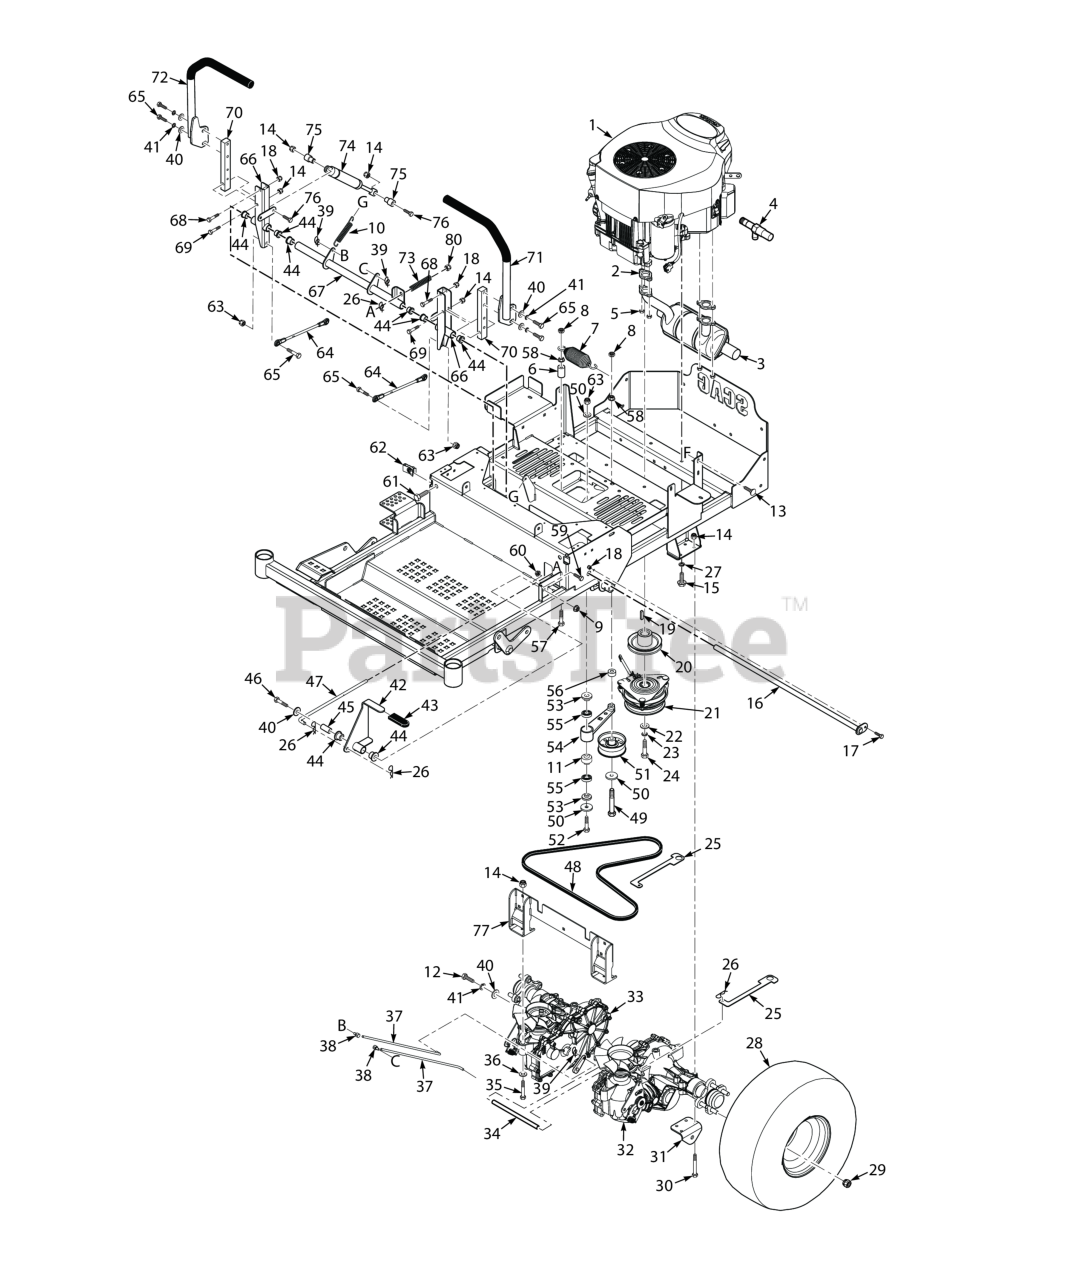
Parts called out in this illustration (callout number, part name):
1	Engine, Kawasaki - FR691V
2	Gasket, Exhaust
3	Muffler, Kawasaki FR651V & FR691V
4	Oil Drain, Kawasaki
5	Nut, M8 x 1.25 Hex Special
6	Spacer, Idler Pulley - SFZ52
7	Spring, Transmission Drive
8	Bolt, Hex Head 3/8-16 x 1" Ser. Flg.
9	Nut, Flange Elastic Stop Nut, 3/8-16
10	Spring, Deck Latch
11	Spacer, Bearing
12	Bolt, Hex Head 3/8-16 x 2-1/4" - 61"
13	Serr. Fl. Hex Head CPSCR, 1/4-20 x 3/4"
14	HEX NUT, ELASTIC STOP LOCK, 5/16-18
15	Bolt, Hex Head 3/8-16 x 1-1/4", Kawasaki FX / FS
16	Shaft Weldment, Control Arm
17	BOLT, HEX HEAD, 1/4-20 X 5/8
18	HEX, NUT, ELASTIC STOP LOCK, 1/4-20
19	Key, 1/4 x 1/4 x 1.25" Pulley Mtg.
20	Pulley, 4-1/2" - 1" Bore
21	Electric Clutch Assembly
22	Flatwasher, 7/16-.469 x 1.75 x .25 (48, 52)
23	Lockwasher, 7/16� Spring
24	Bolt, Hex Head 7/16-20 x 3¼" w/Patch
25	Lever, Dump Valve
26	HAIR PIN, .08 DIAMETER X 1-3/16"
27	Lockwasher, 3/8" Spring, Kawasaki FX / FS
28	Wheel Assembly (48, 52)
30	Bolt, Hex Head 5/16-18 x 3.00"
32	Transaxle, LH - SZL
33	Transaxle, RH - SZL
34	Spacer
35	BOLT, HEX HEAD, 5/16-18 X 2-1/4
37	Rod, Brake
39	Pin, Rue Cotter 3/8" Diameter
40	Flatwasher, 3/8" Special (.391 x .938 x .105)
41	Lockwasher, 3/8" Spring, Kawasaki FX / FS
42	Brake Lever Assembly
43	Grip, Brake Handle
44	Bearing
45	Pivot, Brake Lever
46	Capscrew, Hex Head 3/8-16 x 2-1/2"
47	Rod, Upper Brake Linkage
48	Belt, Transmission -SZL
49	Capscrew, Hex Head 3/8-16 x 3-3/4"
50	Flatwasher, 3/8 (.391 x .938 x .105 HD) Grade 8
51	Pulley, 3-1/2" Dia.
52	Bolt, Hex Head 3/8-16 x 3" - 52"
53	Spacer, Controls
54	Trans. Idler Arm Assy. (Includes 24, 79)
55	BEARINGS, BALL, NEUTRAL RETURN
56	Spacer, Idler Pulley - SFZ61
57	Capscrew, Hex Head 3/8-16 x 2.0"
58	NUT, 3/8-16 SERRATED FLANGE HEX HEAD
59	Capscrew, Hex Head 1/4-20 x 1"
60	NUT, 1/4-20 SERRATED FLANGE HEX HEAD
61	Bolt, Hex Head 3/8-16 x 2-1/2" Soecial Lock
62	U-Nut, 3/8-16
63	HEX NUT, ELASTIC STOP LOCK, 3/8-16
64	Linkage, Pump
65	Bolt, Hex Head 3/8-16 x 1-1/4", Kawasaki FX / FS
66	Bolt, Hex Head 3/8-16 x 1-3/4" (Kohler EFI)
67	Control Arm Assembly
68	Bellcrank Assembly (incl. 44)
69	Bolt, Hex Head, 1/4-20 x 1-1/4"
70	Bolt, Hex Head 5/16-18 x 1-1/2" - Front
71	Bar, Control Lever
72	Handlebar w/Grip
73	Spring, Brake
74	Damper, Steering
75	Spacer, Pump Dampener
76	Bolt, Hex Head 5/16-18 x 1-1/2" (Right Front Engine Mounting, Briggs and Kohler Only)
77	Mounting Weldment, Axle - Hydro-Gear
